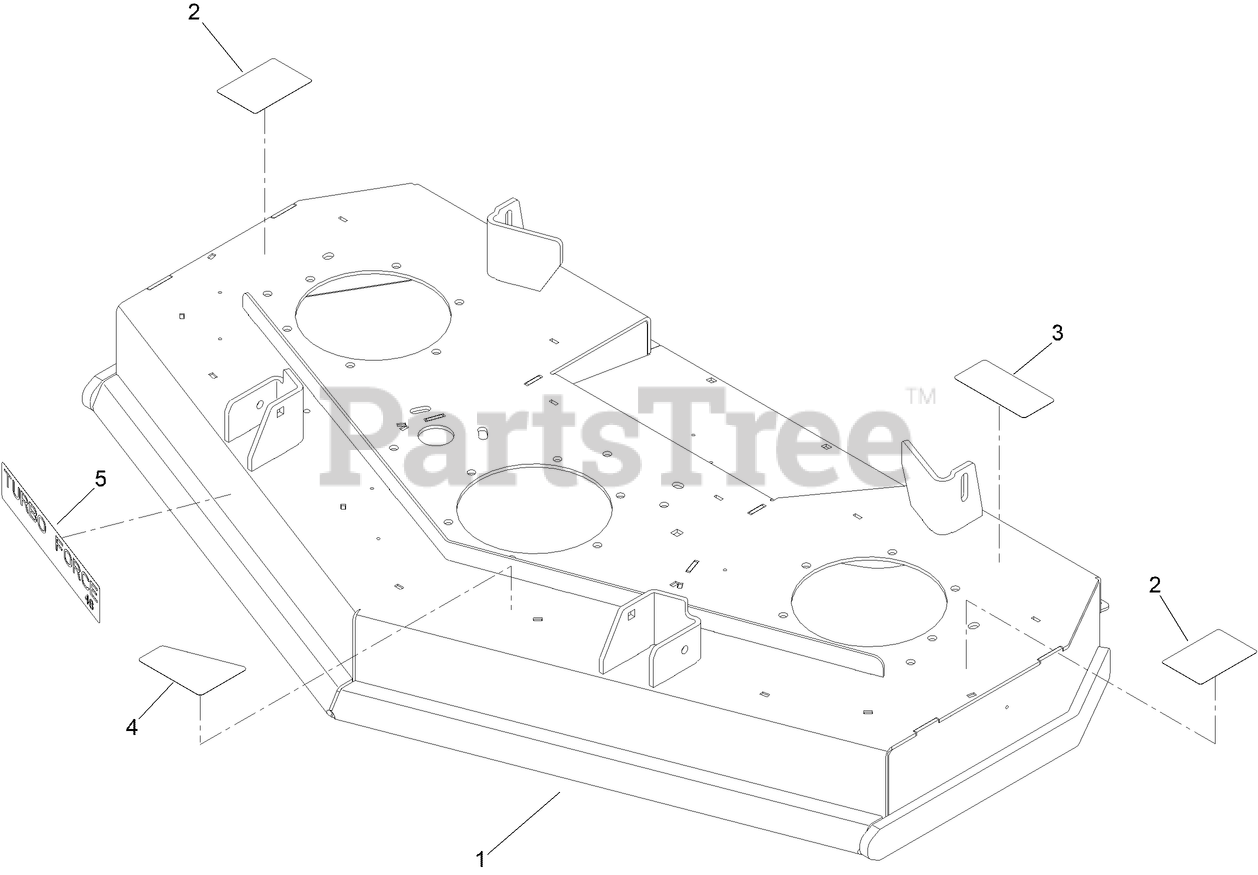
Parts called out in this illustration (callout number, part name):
1	DECK ASM
2	DECAL-DANGER, CE
3	DECAL-BOLT TORQUE
4	DECAL-BELT, TENSION (CE)
